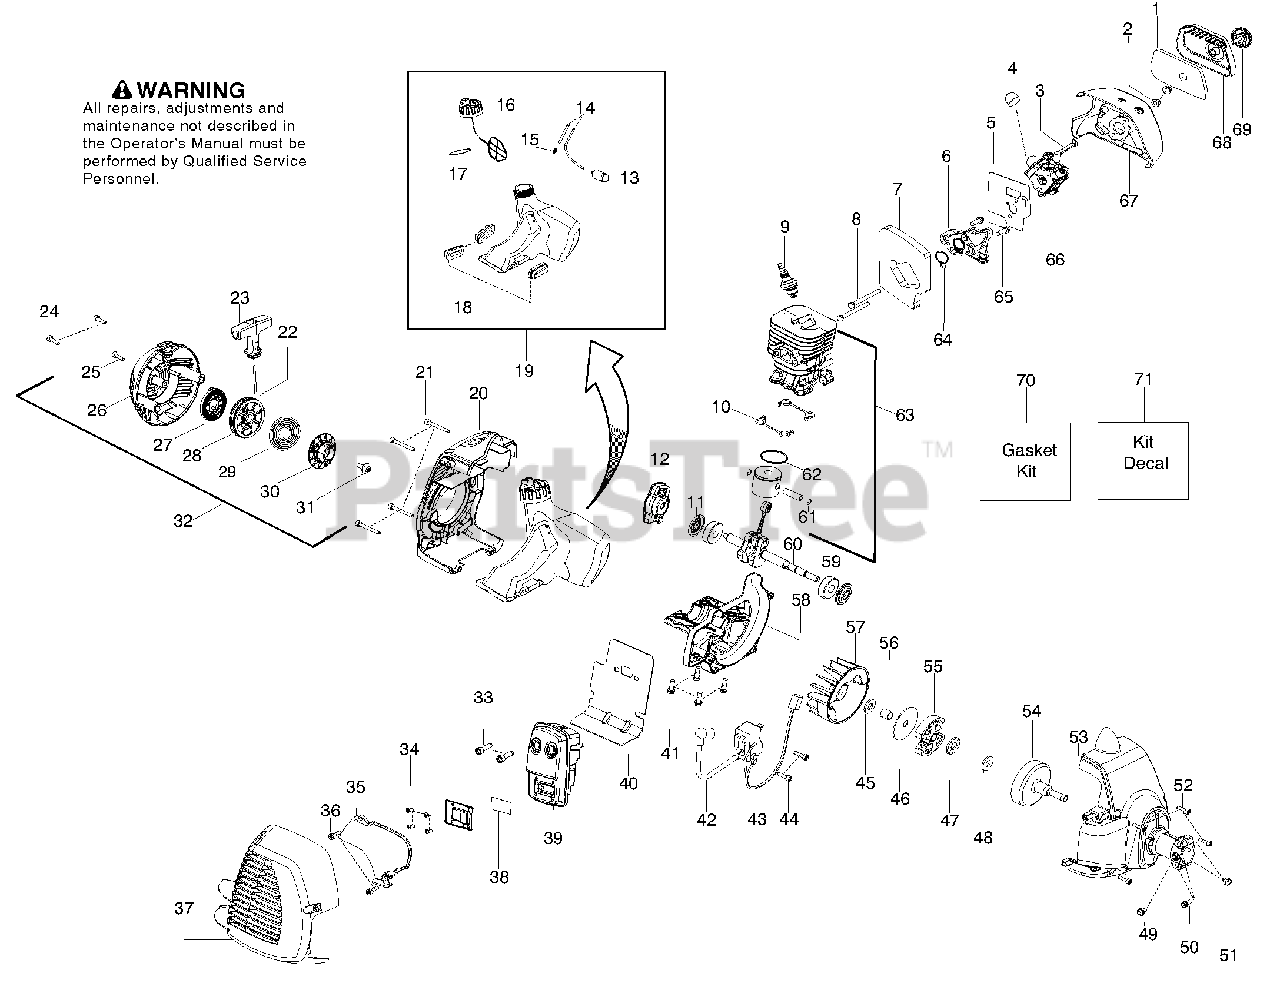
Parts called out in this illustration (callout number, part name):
2	Nut - Carb. Screw
3	Lever - Choke
4	Bulb - Purge
5	Kit - Carb. Gasket
6	Adaptor - Carb.
7	Foam - Gasket (kit)
9	Plug - Spark (RCJ-8Y)
10	Seal - Cylinder (kit)
11	Seal - Crankshaft (kit)
12	Assy - Starter Pawl
13	Assy - Fuel Filter
14	Kit - Fuel Line
15	Fitting - Fuel line
16	Assy - Cap w/ret.
17	O-ring - Fuel Cap (kit)
18	Isolator - Fuel Tank
19	Kit - Fuel Tank Assy.
20	Shroud - Rear (KIT)
22	Kit - Rope
23	Handle - Starter
26	Hsg. - Starter w/eyelet
27	Kit - Spring
28	Kit - Starter Pulley
29	Spring - Driver
30	Pulley - Driver
32	Assy - Starter Hsg.
33	Bolt - Muffler
34	Screw
35	Shield - Heat
37	Kit - Muffler Guard
38	Kit - Spark
39	Kit - Muffler
40	Gasket - Paper Met.(kit)
43	Assy - Leadwire
46	Washer - Clutch
47	Bearing - Thrust
48	Washer - Thrust
49	Screw
50	Screw
53	Assy - Fan Housing
54	Assy - Clutch Drum
55	Assy - Clutch Assy
58	Crankcase - Cast
60	Assy - Crankshaft
61	Retainer - Piston Pin
62	Ring - Piston
63	Kit - Piston/Cyl.
64	Seal - adaptor (kit)
66	Kit - Carb.
67	Airbox
68	Cover - Air Box
69	Assy - Knob
70	Kit - Gasket
71	Kit - Decal
